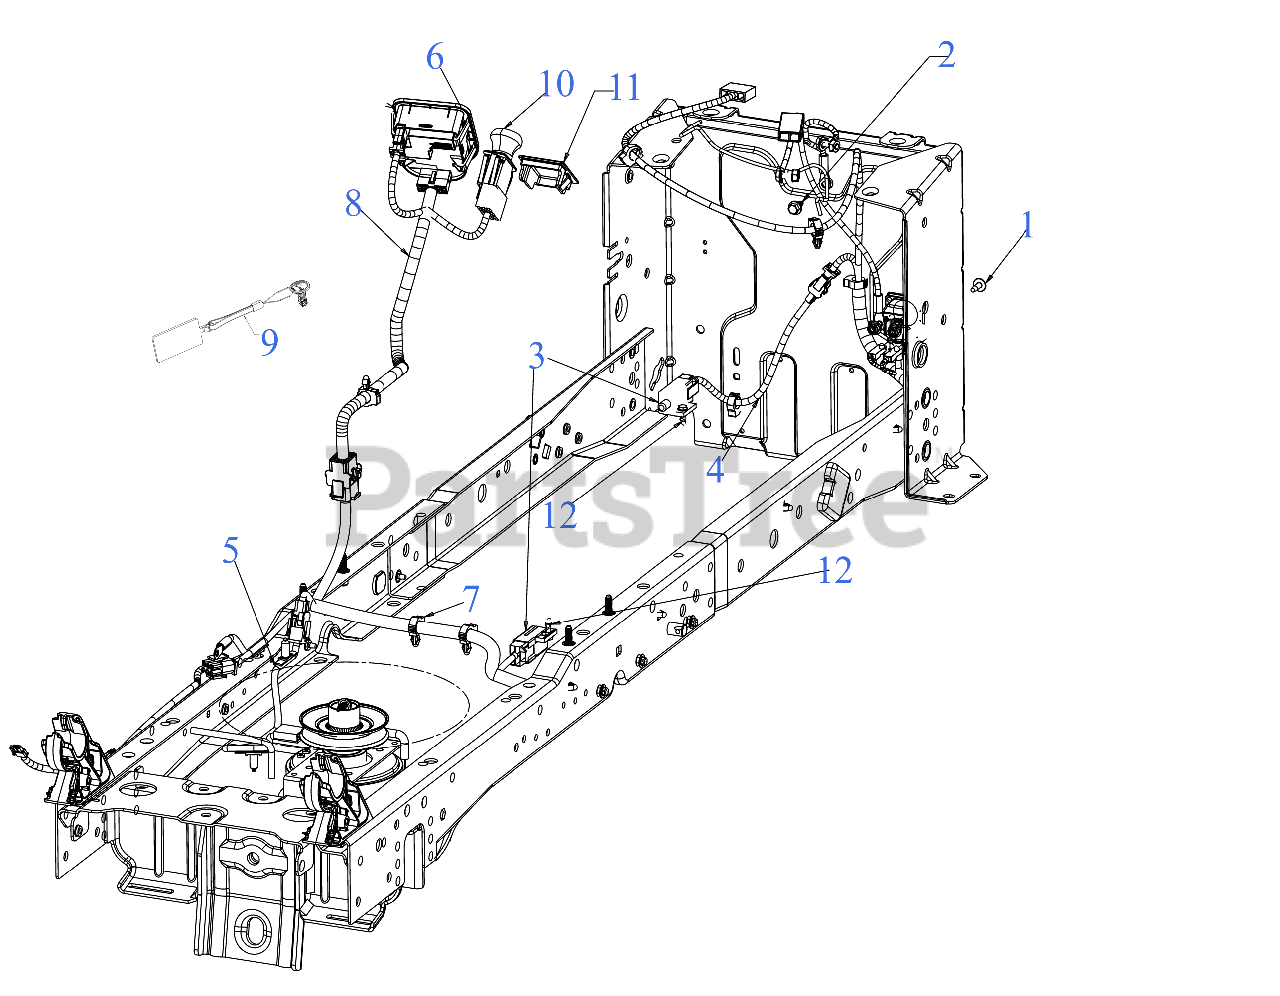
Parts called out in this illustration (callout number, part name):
1	SCREW M6-1 x .625
2	SCREW 1/4-20X.625
3	INTERLOCK SWITCH (NO/NC)
4	REVERSE HARNESS
5	CLUTCH HARNESS 11"
6	MODULE-PBS/HRMTR/SVC MNDR
7	MAIN HARNESS E-PTO/PBS/RMC
8	DASH HARNESS E-PTO/PBS/RMC
9	PBS KEY
10	PTO SWITCH (YELLOW KNOB)
11	DASH HOUR METER PLUG
12	SHOULDER SCREW
